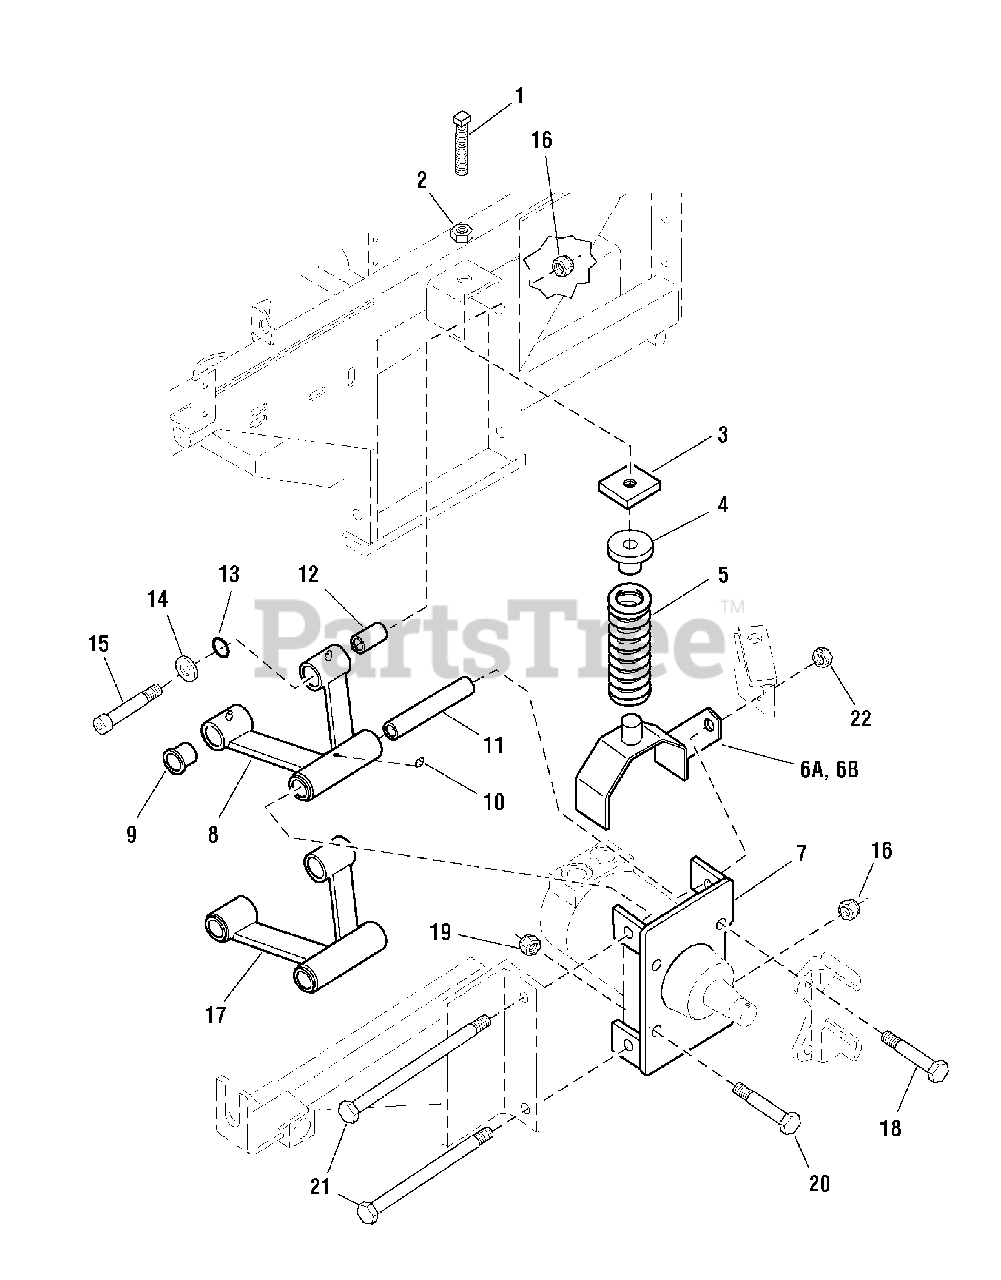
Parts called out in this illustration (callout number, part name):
1	SET SCREW, Square Hd, 1/2-13 x 3
2	NUT, Hex, Jam, 1/2-13
3	SPRING COMPRESSION PLATE
4	SPRING RETAINER
5	SPRING, Suspension
6A	SPRING SADDLE-LH
7	WHEEL MOTOR MOUNT
8	SUSPENSION A-ARM, Upper
9	BUSHING, Flange
10	GREASE FITTING
11	PIVOT SLEEVE, Long
12	PIVOT SLEEVE, Short
14	WASHER, A-Arm
15	CAPSCREW, Allen Head, 1/2-13 x 3
16	NUT, Hex, Nylon Lock, 1/2-13
17	SUSPENSION A-ARM, Lower
18	CAPSCREW, Hex Hd, 1/2-20 x 3
19	NUT, Hex, Nylon Lock, 1/2-20
20	CAPSCREW, Hex Hd, 1/2-20 x 2-1/2
21	CAPSCREW, Hex Hd, 1/2-13 x 6-1/2
22	NUT, Hex, Side Lock, 1/2-13
